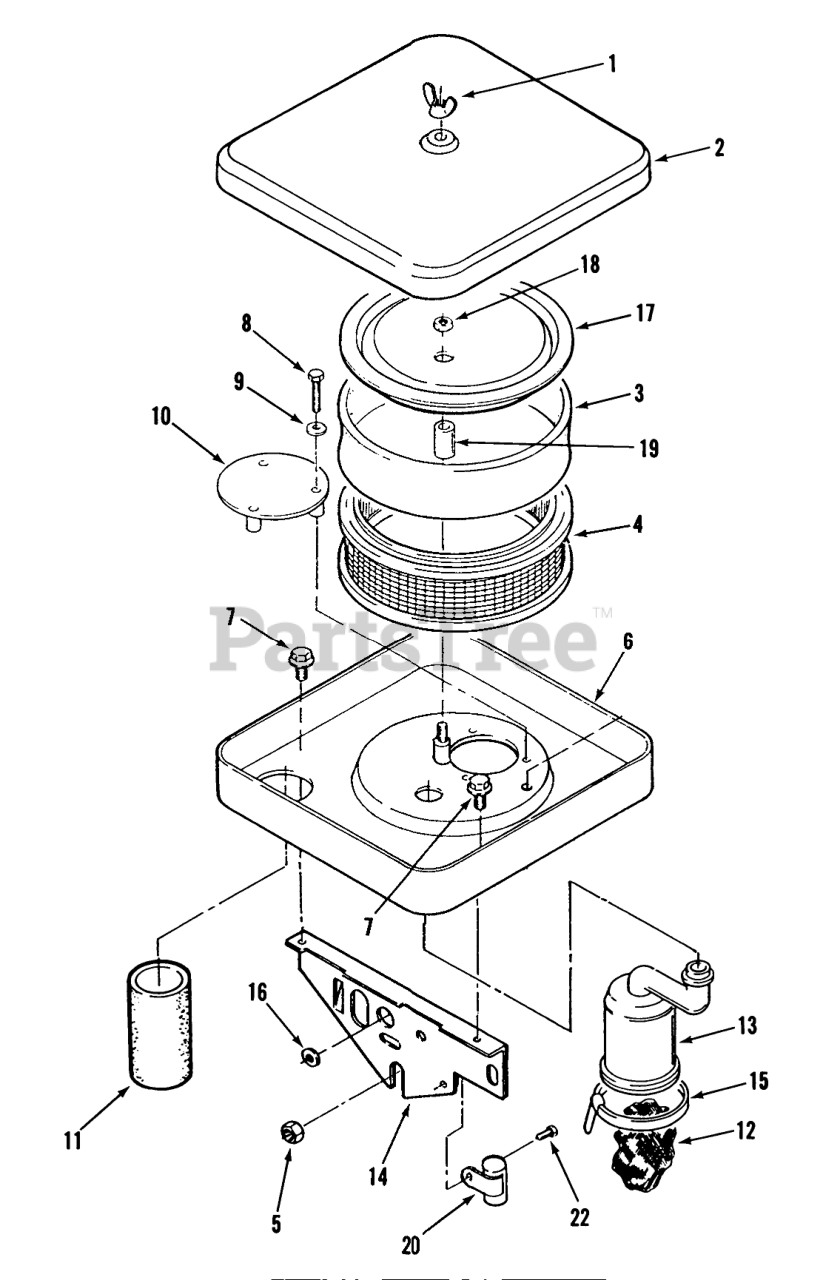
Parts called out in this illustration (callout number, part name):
1	Nut-Wing
2	AIR CLEANER COVER
3	AIR CLEANER ELEMENT
4	Air Cleaner Element
5	Nut
6	Air Cleaner Housing
7	Screw 1/4-20 x 3/8
8	Screw Hex Hd. #10-32 x 1-1/2
9	Flat Washer #10
10	AIR DEFLECTOR PLATE
11	AIR INTAKE TUBE
12	Baffle
13	BREATHER TUBE
14	AIR CLEANER SUPPORT
15	BREATHER TUBE CLAMP
16	Grommet
17	Element Cover
18	Hex Nut 1/4-20
19	Spacer
20	Condenser
22	SCREW #10-32 X 5/8
